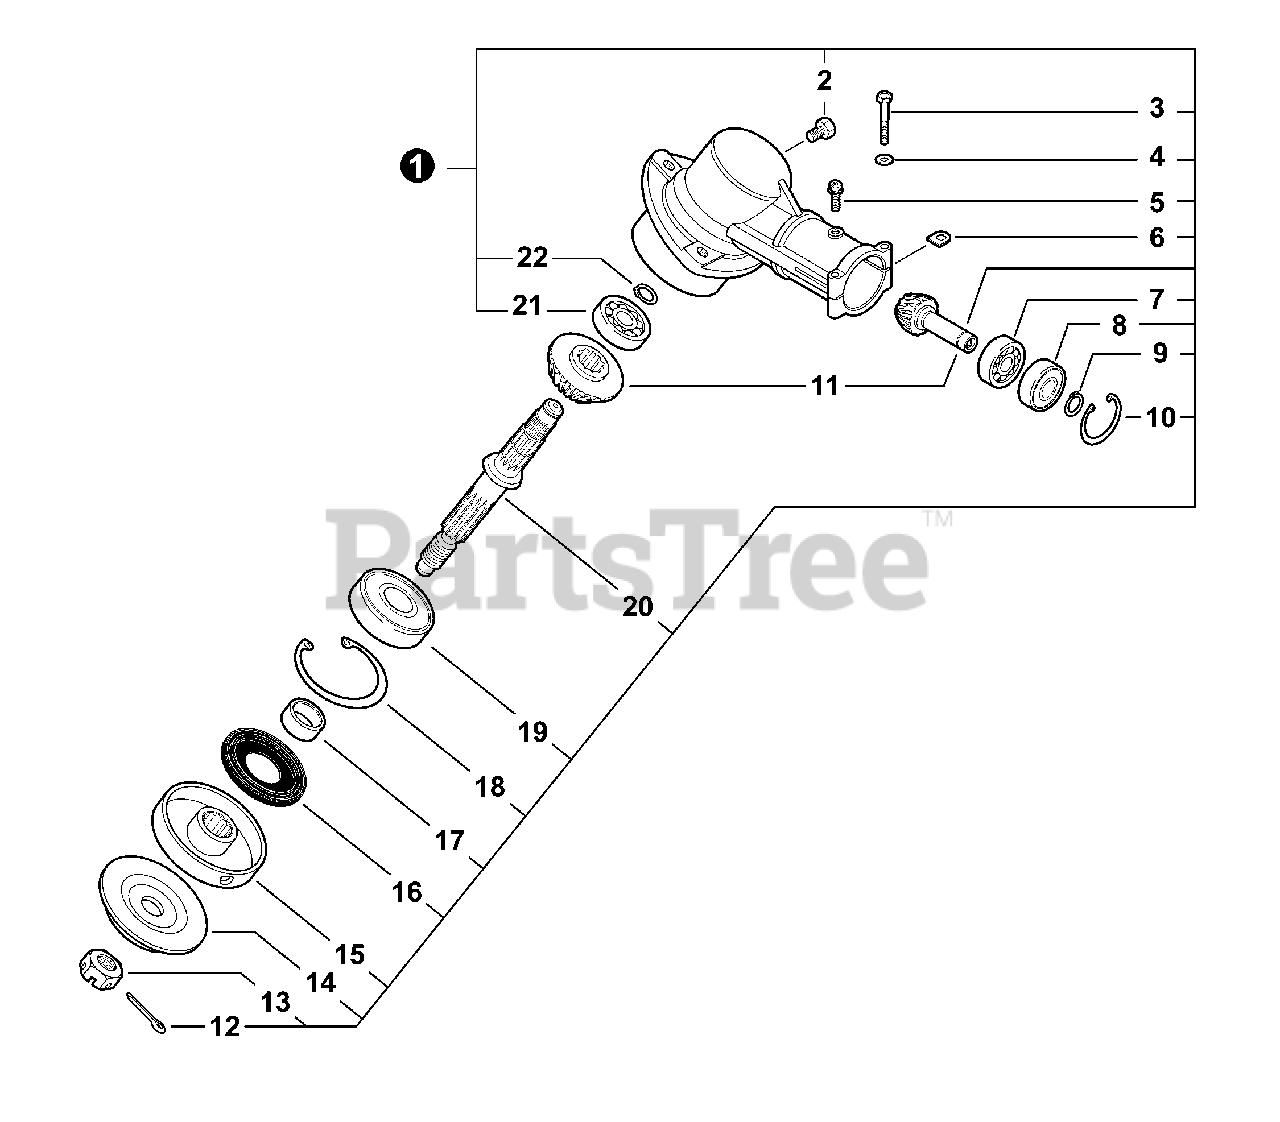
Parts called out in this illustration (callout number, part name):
1	GEAR CASE ASSY
2	BOLT M8×8
3	BOLT 5×35 SP
4	WASHER, FLAT 5.5×10×0.8
5	SCREW 5×10
7	BEARING, BALL 6900
8	BEARING, BALL 6900Z
9	RING, SNAP Ø10
10	RING, SNAP Ø22
11	GEAR SET
12	PIN, COTTER 2×22
14	PLATE, ADAPTOR - LOWER
15	PLATE, ADAPTOR - UPPER
16	SEAL, OIL 22
17	SPACER 11.8×15×9
18	RING, SNAP Ø32
19	BEARING, BALL 6201
20	SHAFT, GEAR
21	BEARING, BALL 609
22	RING, SNAP Ø12
